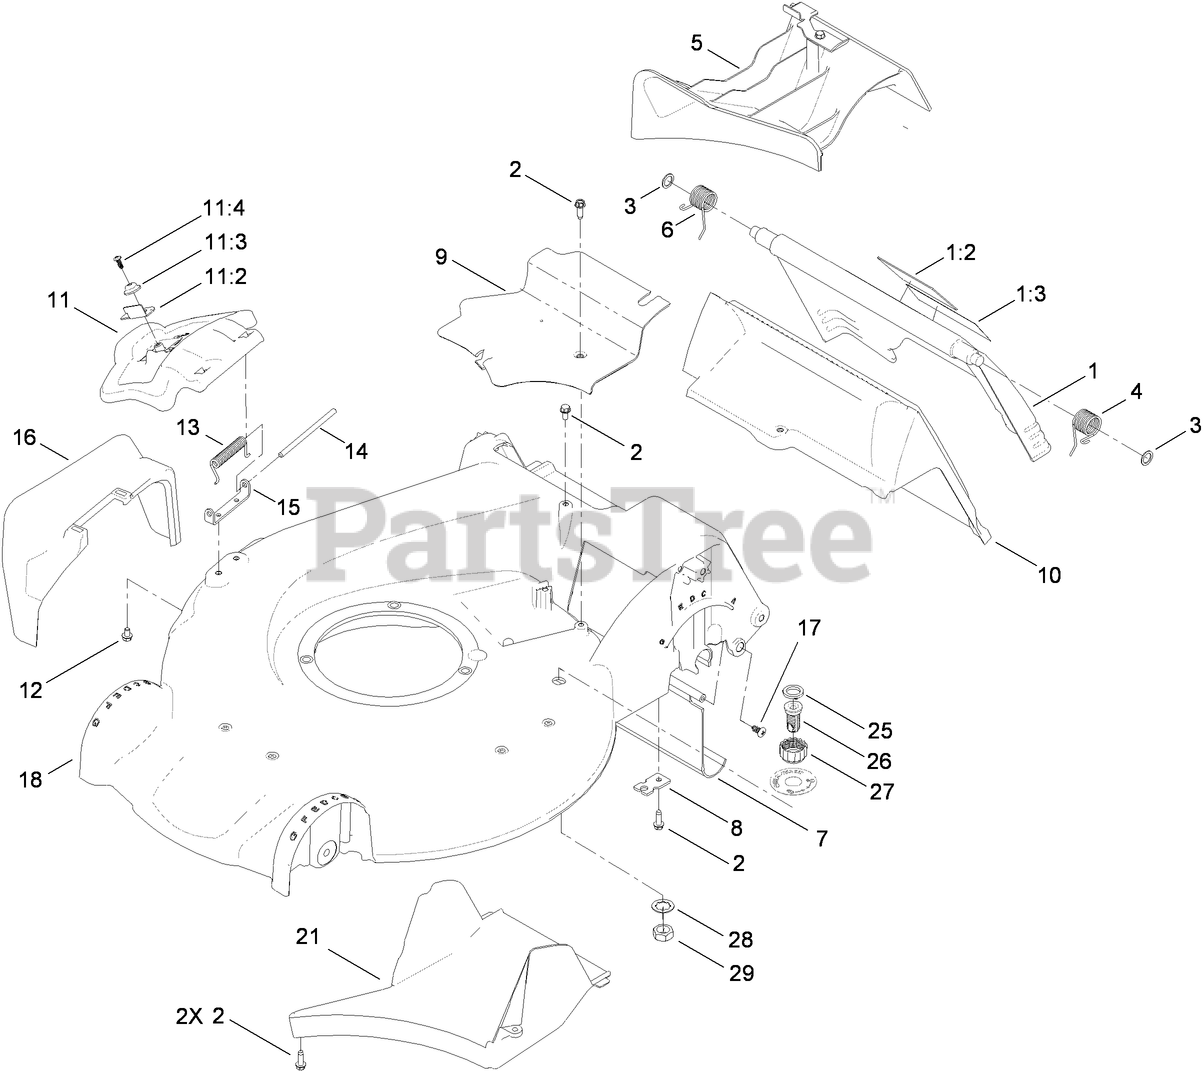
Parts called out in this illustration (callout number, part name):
1	REAR DOOR ASM
1:2	DECAL-WARNING
1:3	DECAL-WARNING
2	SCREW-HWHTF
3	WASHER-NYLON
4	SPRING-TORSION
5	MULCH PLUG ASM
6	SPRING-TORSION
9	COVER-BELT
11	DISCHARGE DOOR ASM
11:2	LATCH-DOOR
11:3	CAP-DOOR
11:4	SCREW-PLASTITE
12	SCREW-HWH
13	SPRING-TORSION
15	BRACKET-COVER
16	CHUTE-DISCHARGE, SIDE
17	SCREW-PTH
18	HOUSING ASM
21	TUNNEL-DISCHARGE
25	WASHER-SEAL, WASHOUT PORT
26	PORT-WASHOUT
27	COUPLING-HOSE, WASHOUT PORT
28	WASHER-LOCK
29	NUT-JAM
